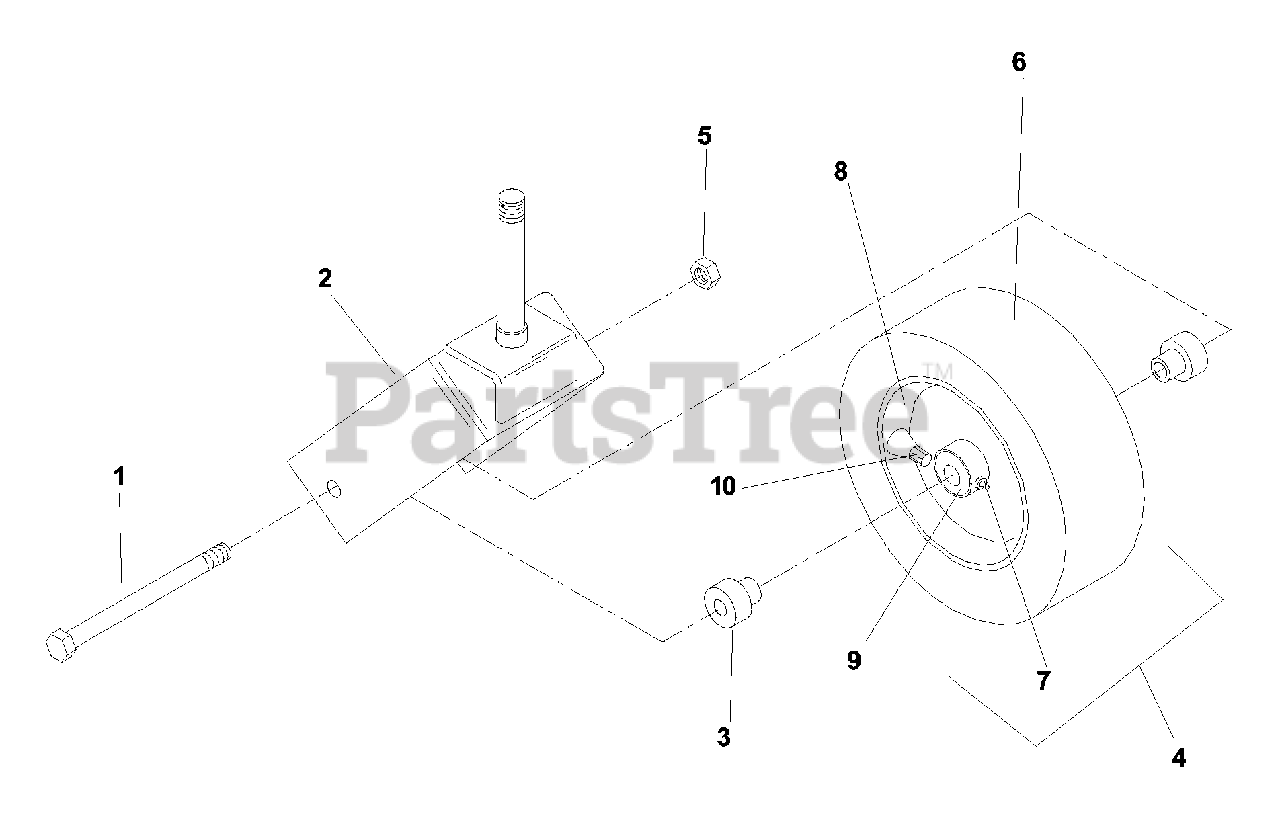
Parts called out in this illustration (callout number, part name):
1	Bolt, 1/2-13 x 9 1/2, GD. 5
2	Yoke, caster
3	Spacer, axle
4	Tire & wheel assembly
5	Nut, 1/2-13, nyloc
7	Zerk
